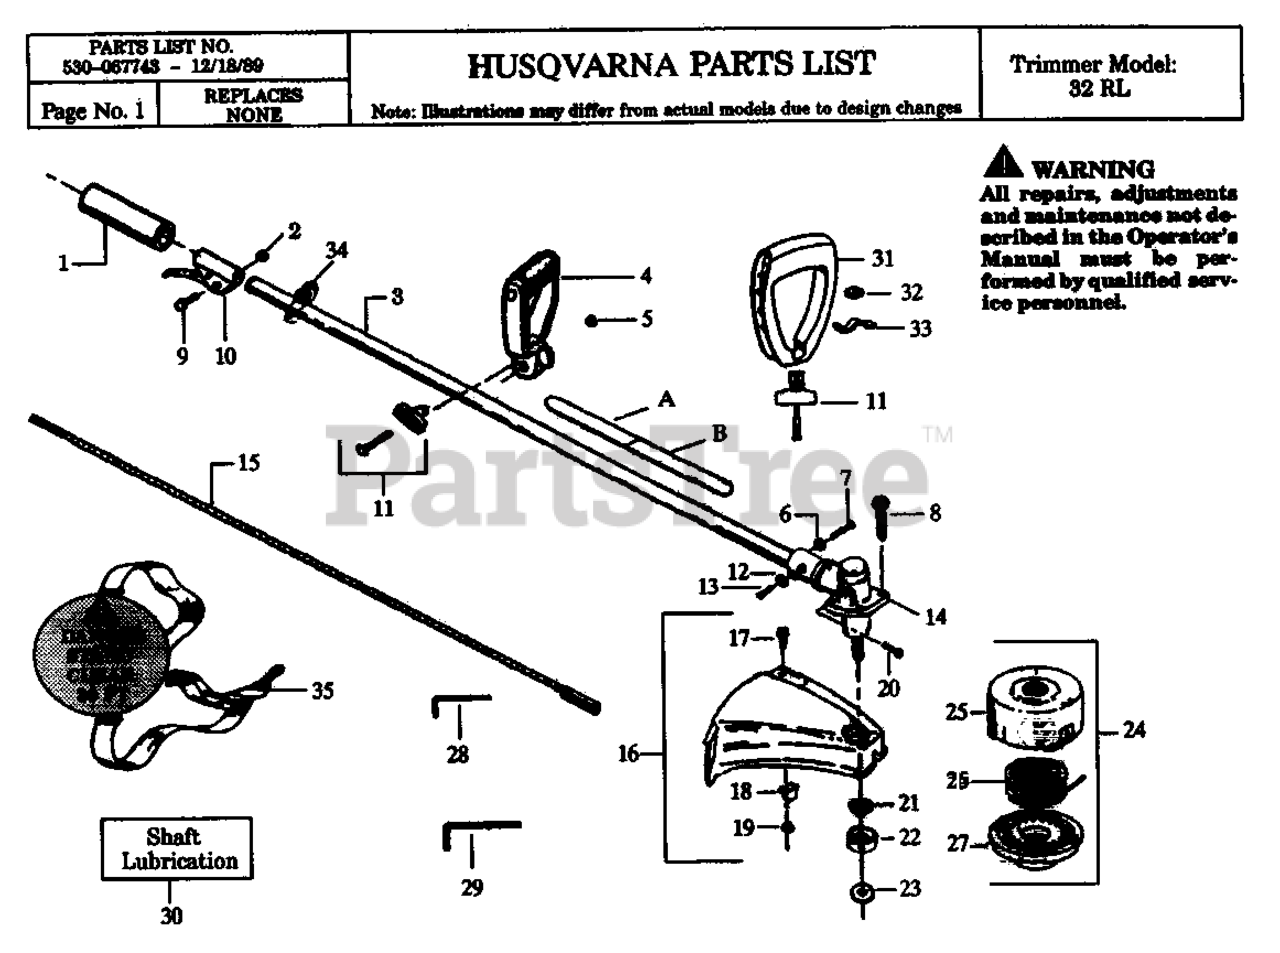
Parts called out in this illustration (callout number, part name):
1	GRIP-DRIVE SHAFT
2	LOCKNUT-HEX 10-24
3	ASSY-DRIVE SHAFT HSG (5
4	ASSY-DRIVE SHAFT HSG (5
5	Handle Ass'y.
7	Lockwasher
8	SCREW-1/4-20X1 HEX SOC
9	SCREW 1/4-10 PLASTITE
10	ASSY-THROTTLE HOUSING
11	KIT "T" HANDLE
12	LOCKWASHER-LOCATOR-TYPE 2
13	SCREW-10-24 X 7/16 (HEX
14	GEAR BOX ASSY/TYPE 1
15	SHAFT-FLEX (53.5")
16	KIT-SHIELD
18	LIMITER-LINE
19	LOCKNUT-(10-24)
23	WASHER-GRASS
24	Cutting Head Ass'y.
25	ASSY-HUB SHAFT & BAL AR
26	Spool w/Line
28	HEX KEY
29	HEX KEY 3/16"
30	GREASE-1/2 FL. OZ.
31	ASSY-HANDLE
32	NUT (1/4-20)
33	CLAMP-ASSIST HANDLE
34	ASSY-CLAMP HARNESS
35	STRAP-SHOULD.W/WARNING
A	Shaft Warning Decal (Upper)
B	Shaft Warning Decal (Lower)
